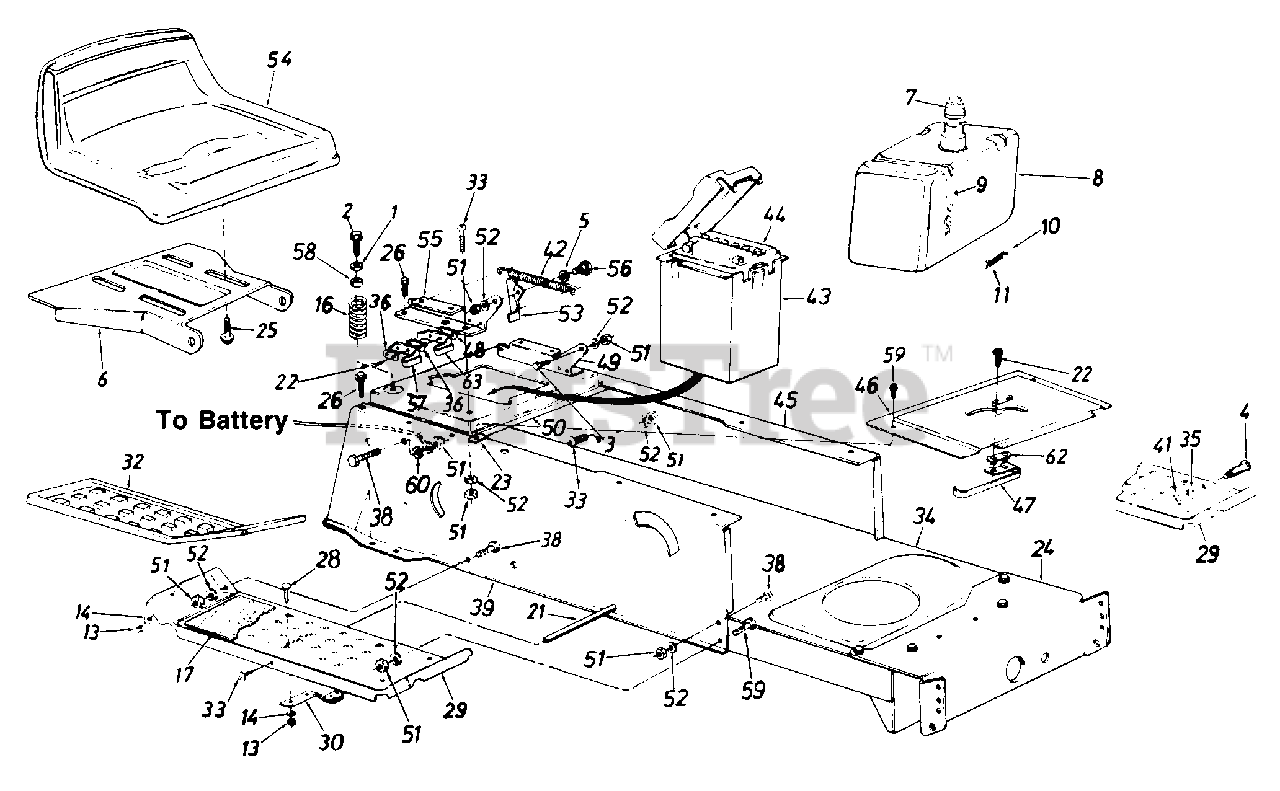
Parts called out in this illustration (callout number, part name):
1	Fl-Wash. .344" I.D. x .875"
2	Hex Wash. Hd. Tap Scr. 5/16-18 x 1.25" Lg.
3	Shld. Bolt .437" Dia. x .162"
4	Shld. Bolt .50" Dia. x .84"
5	Spr-Wash. .445" I.D. x .75
6	Seat Pivot Bracket
7	Fuel Cap w/o Gasket
8	Fuel Tank
9	Tie Strap
10	Fuel Line
11	Hose Clamp
13	Hex Nut 1/4-20 Thd.
14	L-Wash. 1/4" I.D.
16	Compression Spring
17	Foot Pad
21	Running Board Rod
22	Hex Wash. Hd. AB-Tap Scr. #8 x .50" Lg.
23	Speed Nut #10Z
24	Front Pivot Brkt.
25	Hex Tap Scr. 3/8-16 x .75"
26	Hex Wash. Hd. AB-Tap Scr. 5/16 x .75" Lg.
28	Carriage Bolt 1/4-20 x .62"
29	Running Board
30	Blade Brake Ass'y.
32	Rubber Foot Pad L.H.
33	Truss Mach. Scr. 5/16-18 x .75" Lg.
34	Lower Frame
35	L-Wash. 3/8" I.D.
36	Insulator Center Plate
38	Hex Bolt 5/16-18 x .75" Lg.
39	Upper Frame R.H.
41	Hex Nut 3/8-16 Thd.
42	Extension Spring 5.3" Lg.
43	Battery Box w/Cover
44	1 2-V Battery
45	Upper Frame L.H.
46	Shift Cover
47	Reverse Safety Switch
48	Insulator End Plate
51	Hex Nut 5/16-18 Thd.
52	L-Wash. 5/16" I.D.
53	Seat Lift Brkt.
54	Seat 8-7/8" High
57	Spring Switch
58	Bushing
59	Truss Hd. Scr. 5/16-18 x 1.0" Lg.
60	External L-Wash. 5/16" I.D.
62	Insulator Nut Plate
63	Safety Switch (Seat)
